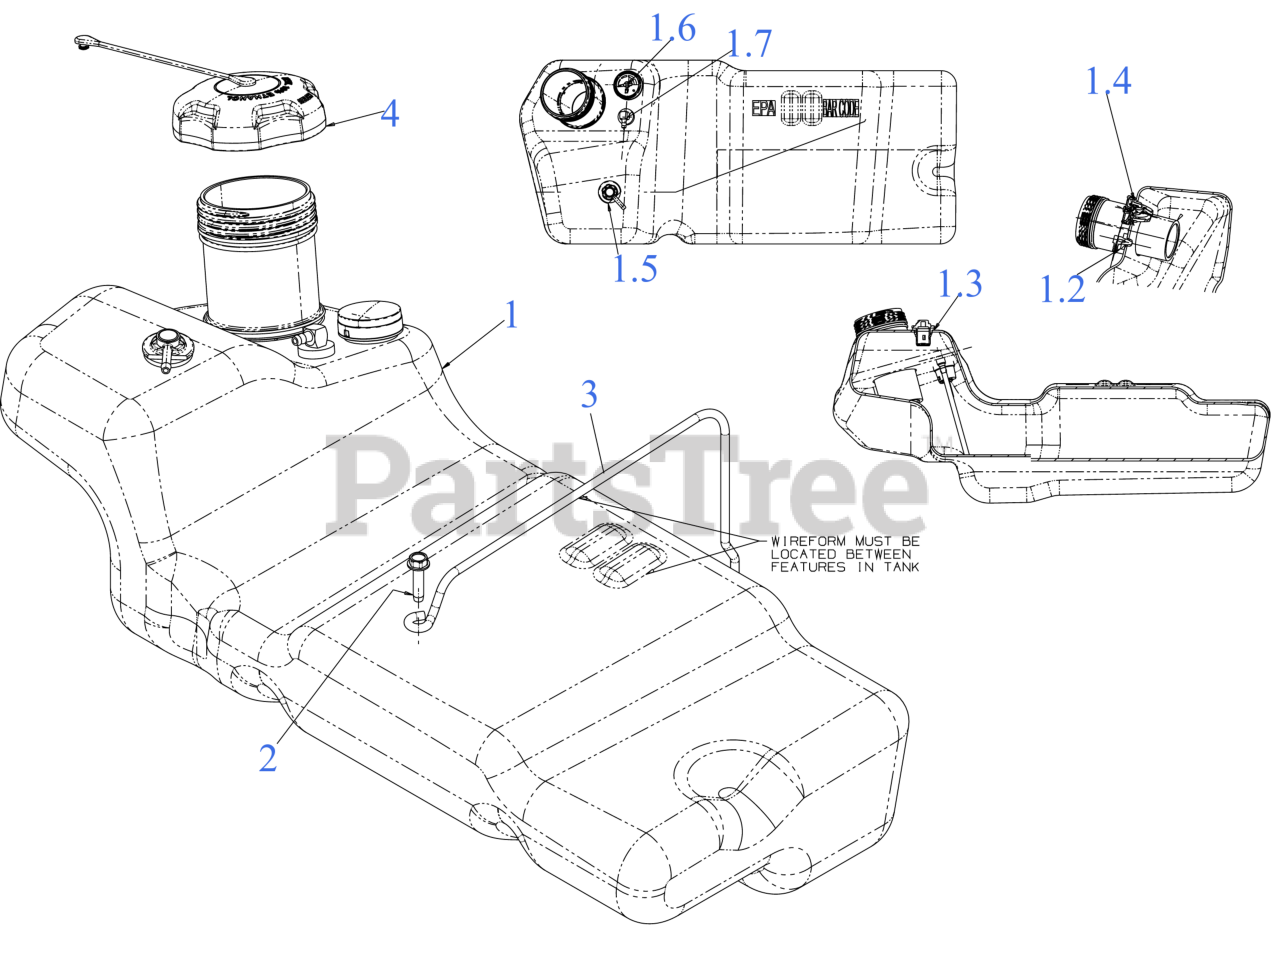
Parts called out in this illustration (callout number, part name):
1	FUEL TANK (5.5 GAL)
1.3	RUBBER GROMMET 23.0 ID x 35.5 OD
1.4	GROMMET 1.174X1.400X0.505
1.5	ROLLOVER FUEL VALVE
1.6	FUEL GAUGE 8.5"
1.7	FUEL PICKUP ASSEMBLY
2	SCREW 5/16-18 x 1.25
3	FUEL TANK RETAINER
4	FUEL CAP (W/TETHER)
